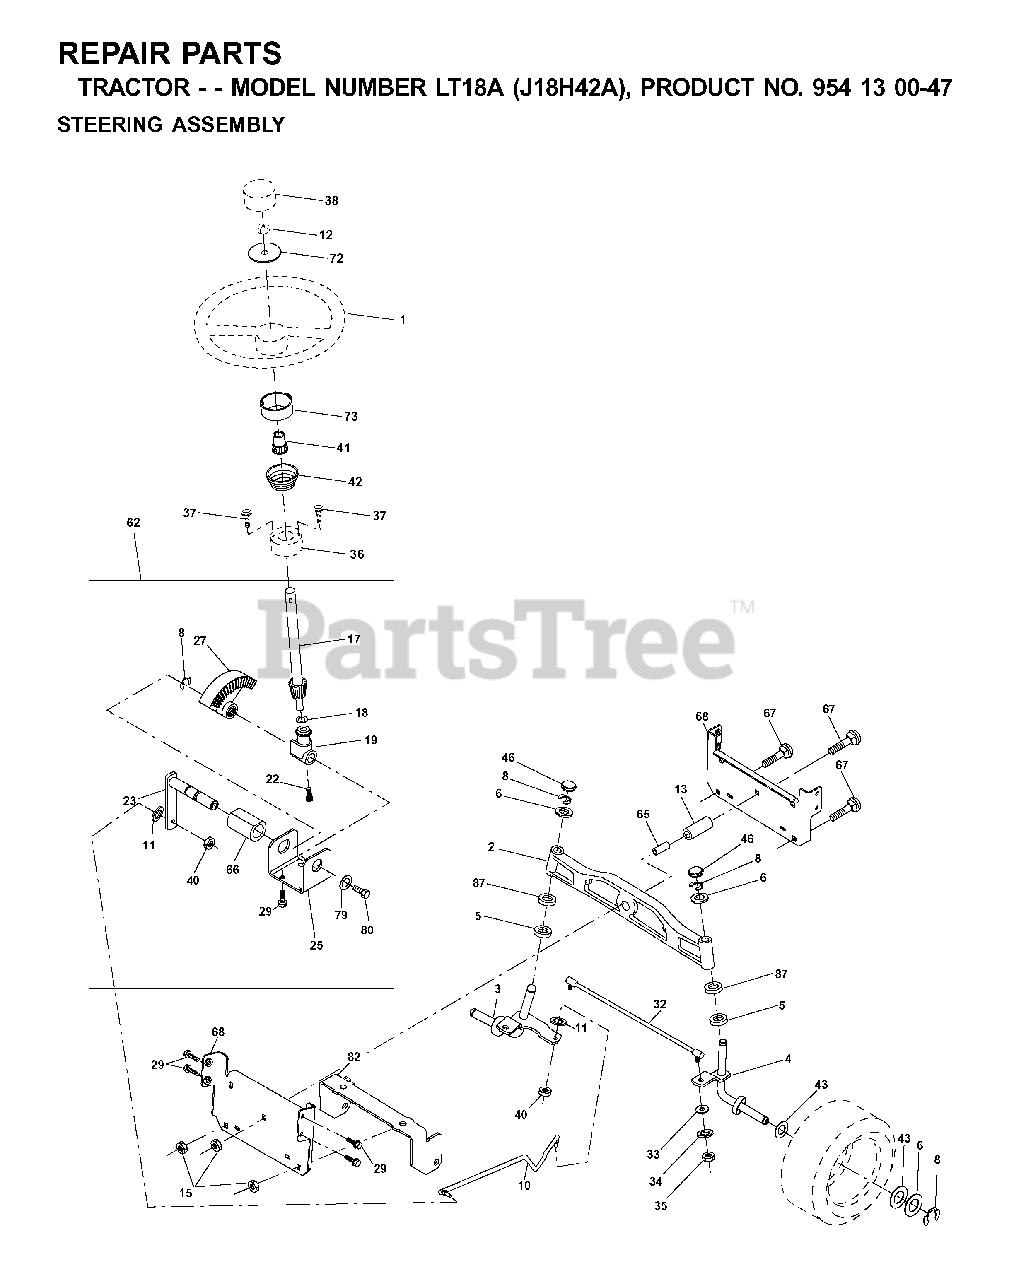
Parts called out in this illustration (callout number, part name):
2	AXLE ASM
3	SPINDLE.ASM.LH.15"TIRES
4	SPINDLE.ASM.RH.15"TIRES
8	RING CLIP
10	DRAGLINK.15".TIRES
11	WASHER, LOCK 3/8
12	NUT.HEX.1/2-20
13	TUBE, PIVOT AXLE
15	NUT
17	STEERING SHAFT
18	THRUST WASHER
19	STEERING SHAFT SUPPORT
22	SCREW.HX.WSH.HD
23	SHAFT ASSY PITTMAN
25	BRACKET STEERING
27	GEAR.SECTOR
29	SCREW 3/8-16X3/4
33	WASHER M
34	LOCKWASHER
35	NUT, CROWNLOCK
36	BUSHING, STRG. BLK
40	GRIPCO NUT
41	STEERING WHEEL ADAPTOR
46	CAP.SPINDLE
65	SPACER BRACE AXLE
66	BEARING ARM
67	BOLT
68	BRACE.AXLE.15"TIRES
80	BOLT.HX.NYLON3/8-16X
82	BRACKET
85	FASTENER.XMAS.TREE
87	WASHER, FLAT .781 X 1 1/2"
